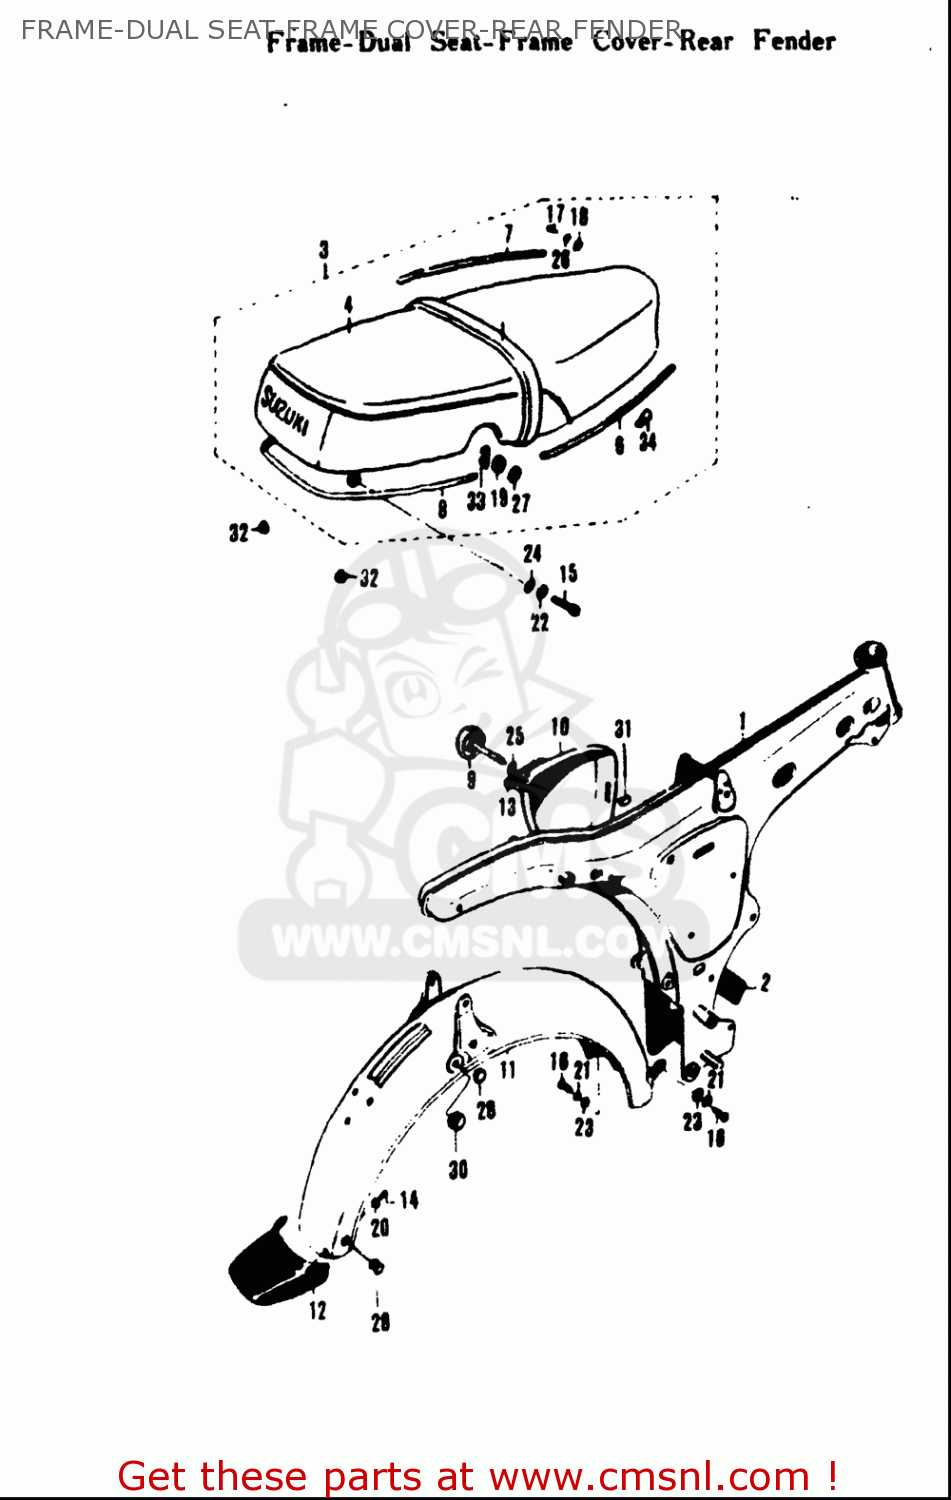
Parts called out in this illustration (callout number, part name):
14	BOLT
15	BOLT
16	BOLT
18	NUT
19	NUT
20	WASHER,LOCK
21	WASHER,LOCK
22	WASHER,LOCK
23	WASHER
24	WASHER
25	NUT
27	WASHER(6.5X18X1.6)
32	CUSHION(11.5X22X20)
33	CLIP
